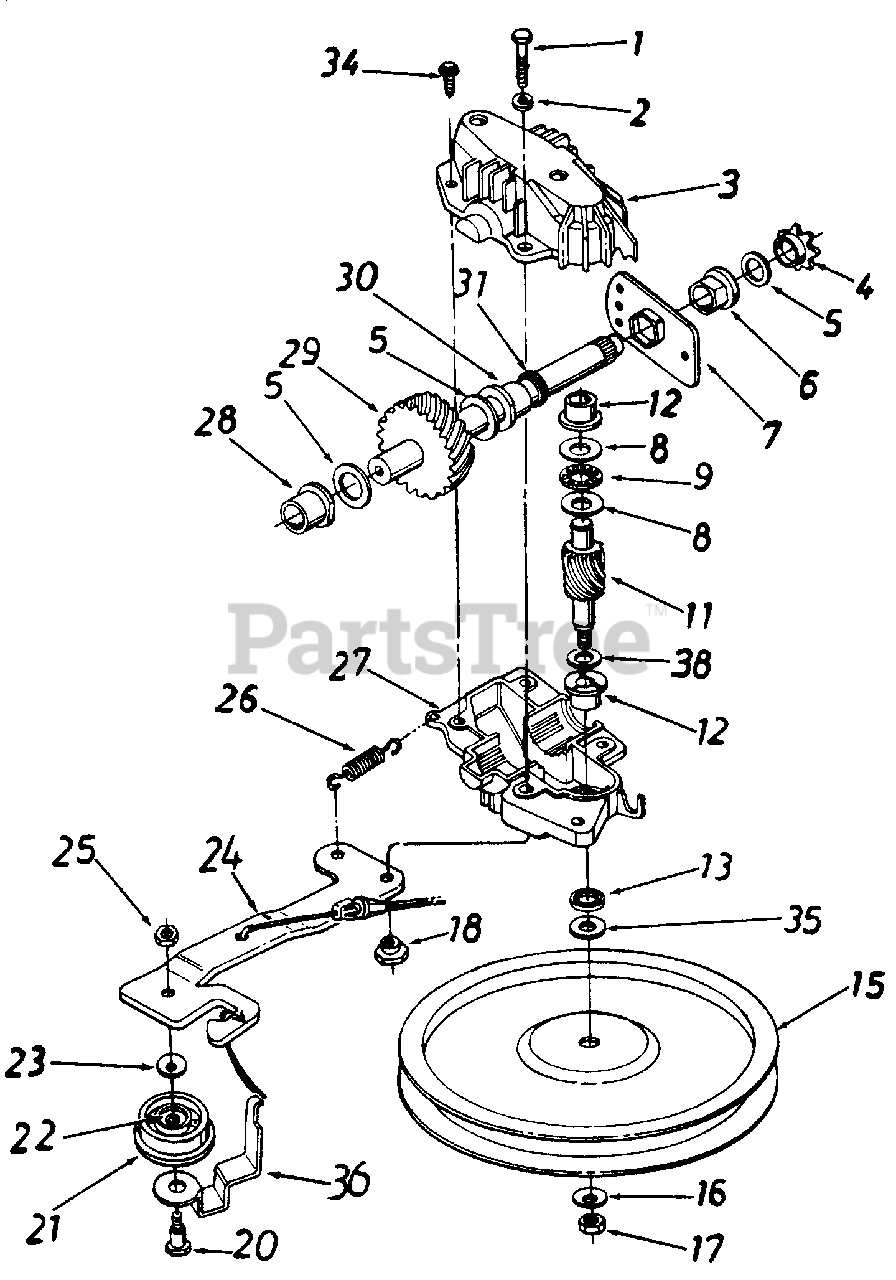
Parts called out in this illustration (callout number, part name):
1	Hex Bolt 1/4-20 x 1.25" Lg. w/Patch
2	L-Wash. 1/4" I.D.
3	Upper Hsg. Half
4	6 Tooth Sprocket
5	Fl-Wash. 5/8" I.D. x .030
6	Hex Flange Brg..631" I.D.
8	Thrust Wash..382" I.D. x .70" O.D.
9	Thrust Bearing .375" I.D. x .812" O.D.
11	10 Tooth Helical Gear
12	Flange Bearing
13	Oil Seal
15	Fl-Pulley 5.06" I.D.
16	Bell-Wash..265" I.D. x .75"
17	Hex Nut 1/4-28 L.H. Thd.
18	Shld. Spacer .375" Dia. x .170
20	Shld. Bolt .375" Dia. x .40"
21	Fl-Idler Plastic 1.50" Dia.
22	Needle Brg..375" x .31"
23	Bell-Wash..265" I.D. x .75"
24	Idler Brkt. Ass'y.
25	Hex patch L-Nut 1/4-28 Thd.
26	Extension Spring 1,12" Lg.
27	Lower Hsg. Half
28	Flange Bearing .56 Dia.
29	34T: Helical Gear
30	Flange Bearing .629 Dia.
31	Oil Seal .625 Dia.
34	Hex B-Tap Scr. #10 x .62"
35	Hex Washer .26" x .88"
36	Belt Keeper
38	Fl-Wash.
